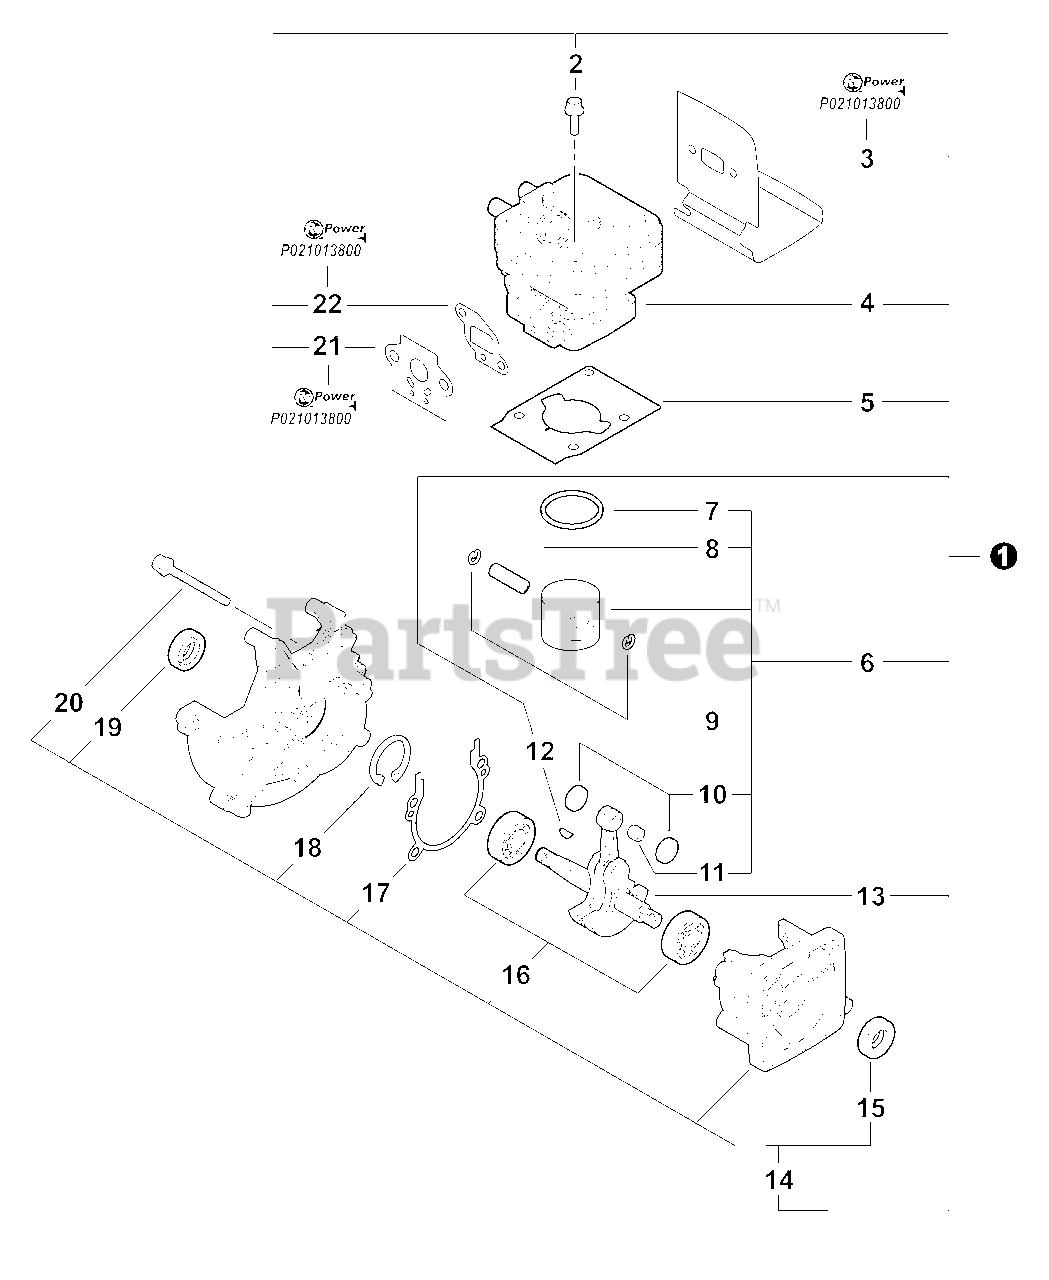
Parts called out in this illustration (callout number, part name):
1	SHORT BLOCK
2	SCREW 5×25
3	HEAT SHIELD, EXHAUST
4	CYLINDER
5	GASKET, CYLINDER
6	PISTON KIT
7	RING, PISTON
8	PIN, PISTON
9	RING, SNAP
10	WASHER, THRUST
11	BEARING, NEEDLE 9
12	KEY, WOODRUFF
13	CRANKSHAFT ASSY
14	CRANKCASE KIT
15	SEAL, OIL 12
16	BEARING, BALL - 6201 C3
17	GASKET, CRANKCASE
18	RING, SNAP Ø32
19	SEAL, OIL 12
20	BOLT 5×28
21	GASKET, INTAKE
22	GASKET, INTAKE
